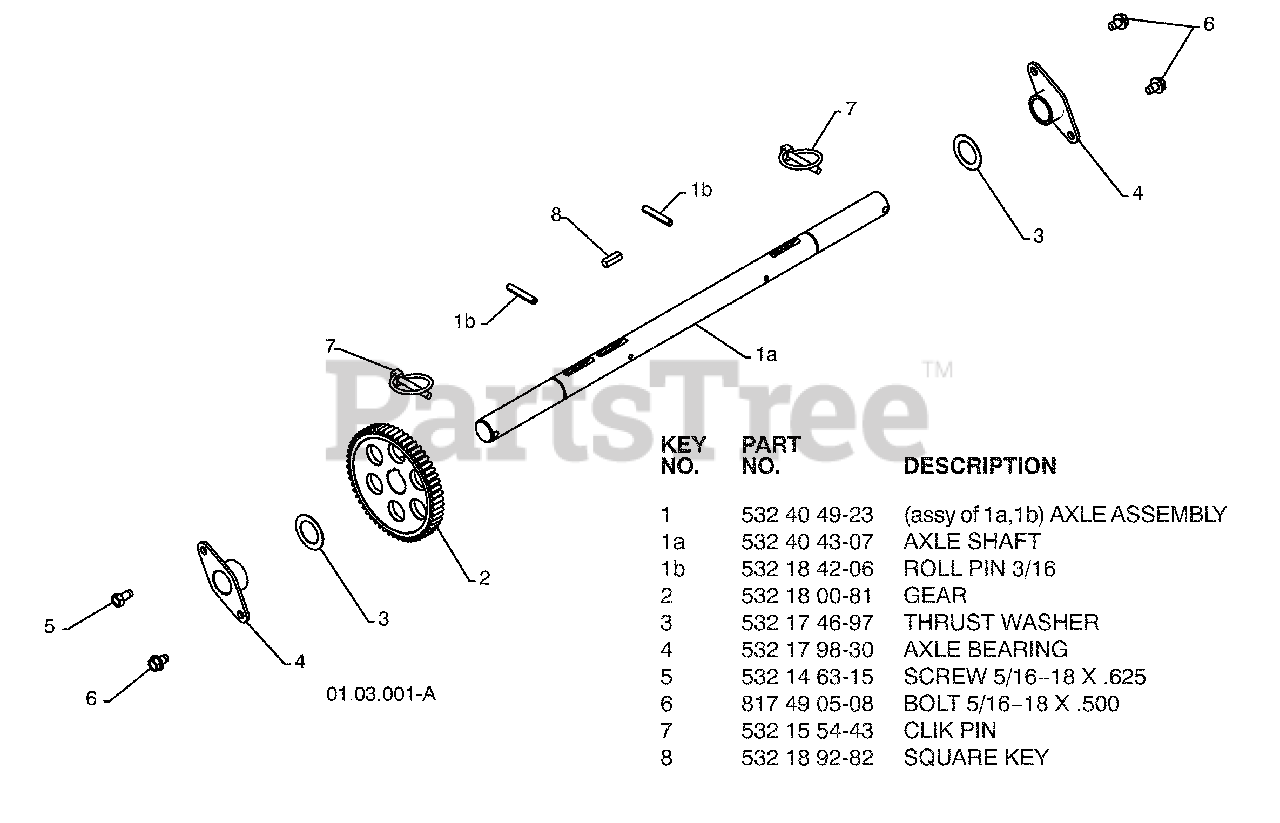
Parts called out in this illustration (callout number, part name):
1	(assy of 1a,1b) AXLE ASSEMBLY
2	GEAR
3	THRUST WASHER
4	AXLE BEARING
5	SCREW 5/16-18 X .625
6	BOLT 5/16-18 X .500
8	SQUARE KEY
